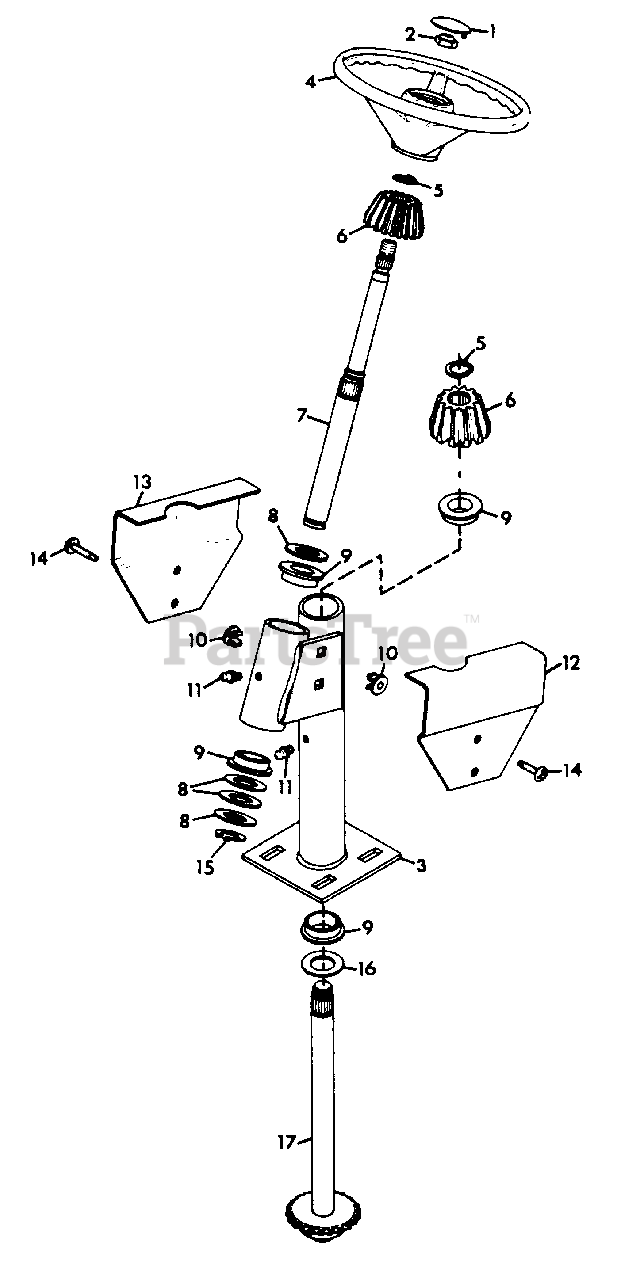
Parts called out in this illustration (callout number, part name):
1	CAP, STEERING WHEEL
2	NUT, LOCK 5/8-11
3	TUBE, STEERING
4	WHEEL, STEERING
5	RING, RETAINING
6	PINION, BEVEL
7	SHAFT, STEERING WHEEL
8	RACE, BEARING THRUST
9	BEARING, FLANGED
10	GROMMET, PLASTIC
11	FITTING, LUBE 1/4-28
12	GUARD, STEERING L.H.
13	GUARD, STEERING R.H.
14	SCREW, 1/4-20X.50
15	RING, RETAINING
16	RACE, BEARING THRUST
17	SHAFT, STEERING
